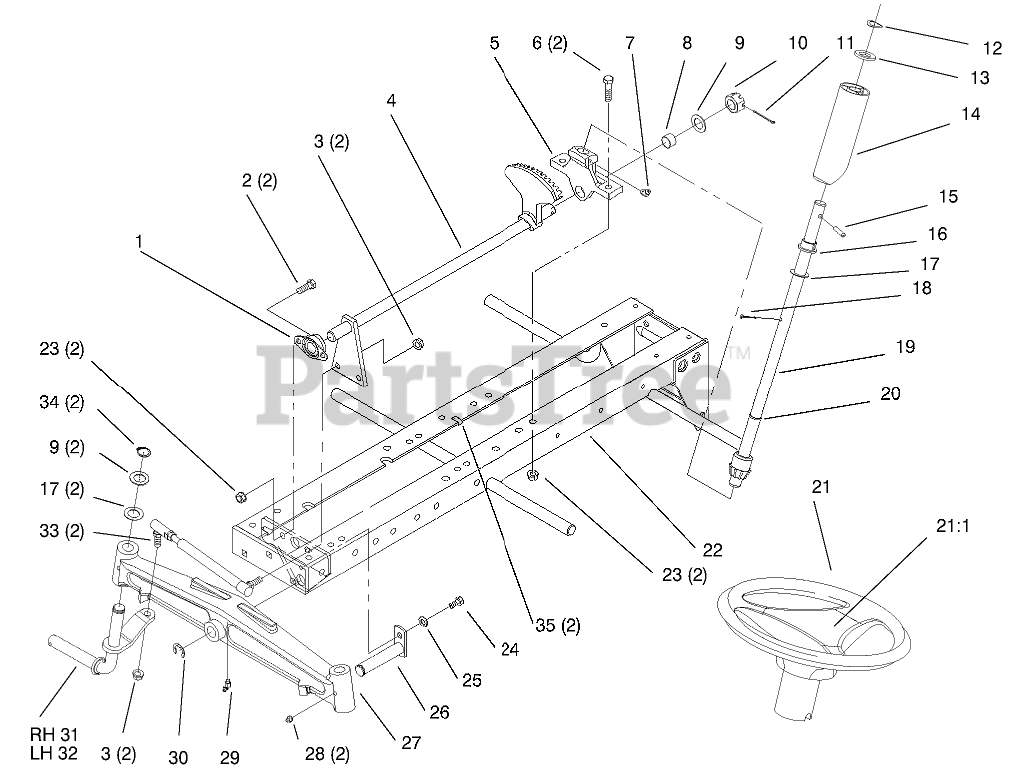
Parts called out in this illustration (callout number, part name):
1	BEARING-FLANGED
2	SCREW-HH
3	NUT-LOCK
4	Shaft
5	Support-Steering
6	SCREW-HH
7	FITTING-GREASE
8	BEARING-BRONZE
9	WASHER
10	NUT-HEX, SLOTTED
11	PIN-COTTER
12	WASHER-BOWED
13	WASHER-FLAT
14	TUBE-STEERING
15	PIN-ROLL
16	BEARING-FLANGED
17	PIN-COTTER
17	WASHER-SHIM
19	STEERING SHAFT ASM
20	O-RING
21	WHEEL - STEERING 15"
21:1	COVER-WHEEL
22	Frame
23	NUT-LOCK, NI
24	SCREW-HH
25	WASHER-LOCK
26	PIN AND PLATE ASM
27	AXLE-FRONT
28	FITTING-GREASE
30	E-RING
31	RH SPINDLE WA
32	LH SPINDLE ASM
33	ASM-Rod
34	RING-RETAINING
35	CLIP-WIRE
